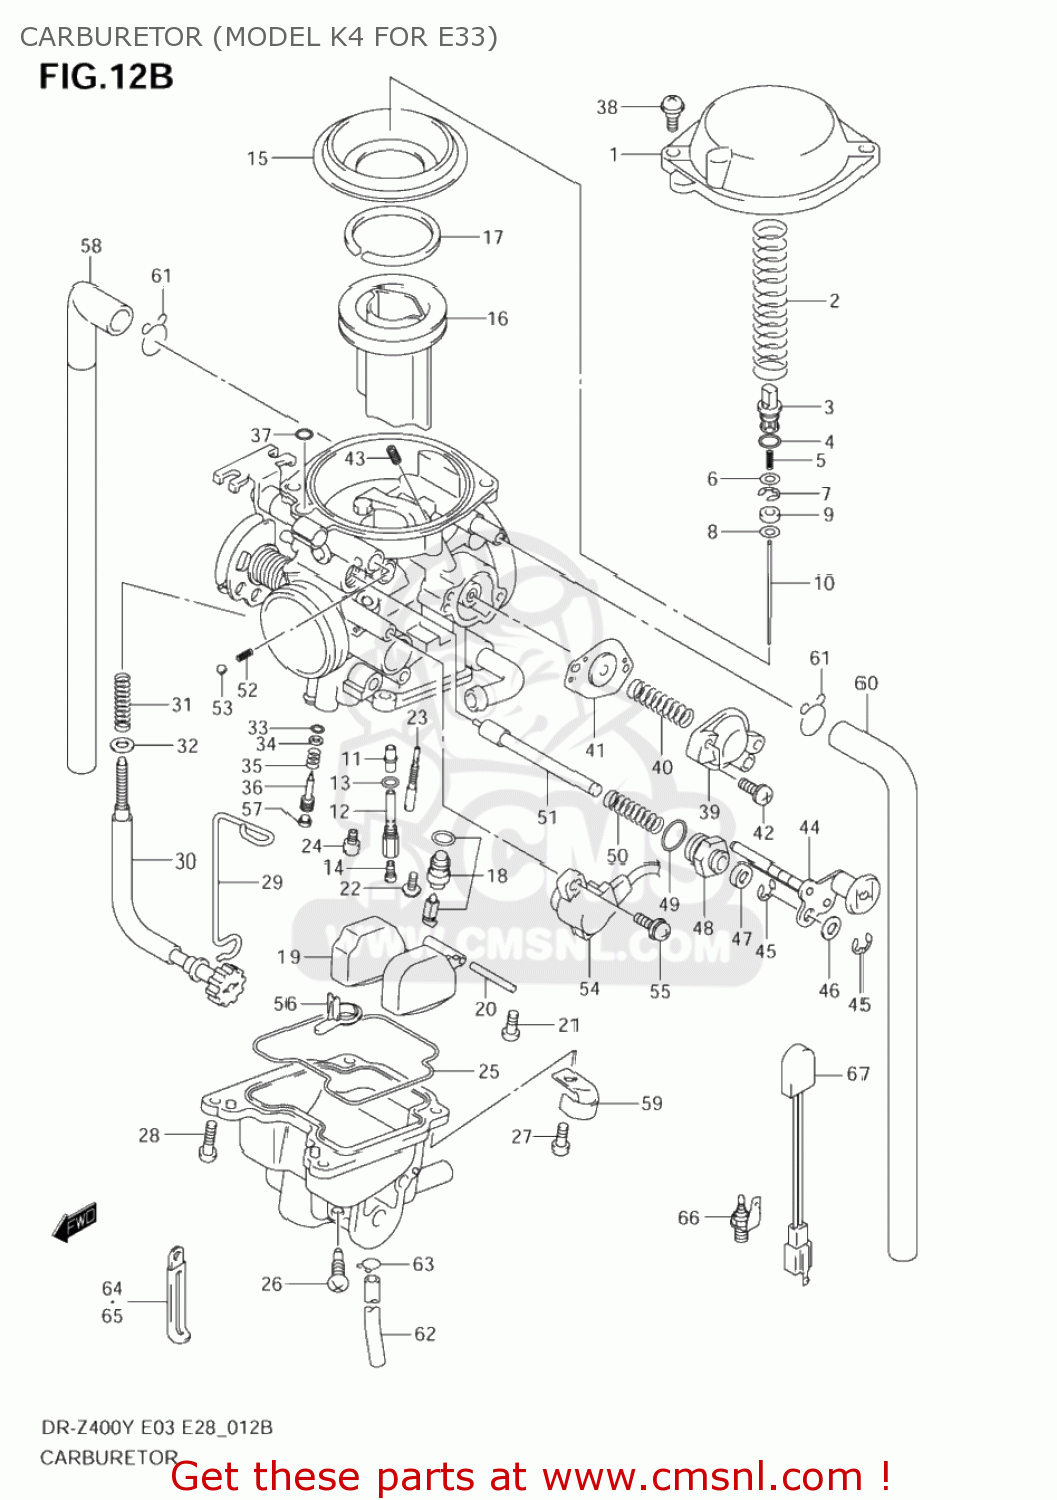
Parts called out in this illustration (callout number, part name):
1	COVER,DIAPHRAGM
2	SPRING
3	HOLDER
4	O RING(D:1.9,ID:4.8)
5	SPRING
6	WASHER
7	E RING,MULTIPLE JET NOZZLE
8	RING
9	WASHER
10	NEEDLE,JET
11	JET,NEEDLE
12	HOLDER,JET
13	O RING
14	JET,MAIN(140)
15	DIAPHRAGM
16	VALVE,PISTON
17	RING
18	VALVE ASSY,NEEDLE
19	FLOAT ASSY
20	PIN,FLOAT
21	SCREW
22	SCREW
23	JET,PILOT(22.5)
24	JET,MAIN(62.5)
25	GASKET (NAS)
26	SCREW,DRAIN
27	SCREW
28	SCREW
29	CLIP
30	SCREW,ADJUST
31	SPRING,THROTTLE SCREW
32	WASHER,STARTER SHAFT
33	O RING,PILOT AIR SCREW
34	WASHER
35	SPRING,THROTTLE SCREW
36	ADJUSTER
37	O RING
38	SCREW
39	COVER ASSY
40	SPRING
41	DIAPHRAGM ASSY
42	SCREW
43	JET,PILOT AIR(155)
44	PLATE ASSY
45	E RING
46	WASHER
47	CAP,STARTER VALVE
48	GUIDE SCREW,PLUNGER
49	O RING
50	SPRING
51	PLUNGER ASSY
52	SPRING
53	BALL,CARBURETOR
54	SENSOR ASSY
55	SCREW
56	RING
57	PLUG
58	PIPE,RUBBER
59	PLATE
60	HOSE,AIR VENT(6.5X10.5)
61	CLIP
62	HOSE,OVER FLOW(4.5X8X400)
63	CLIP
64	CLAMP(L:65)
65	CLAMP(L:120 T:1.0)
66	HEATER ASSY,CARBURETOR(15W)
67	THERMO SWITCH,CARB HEATER
